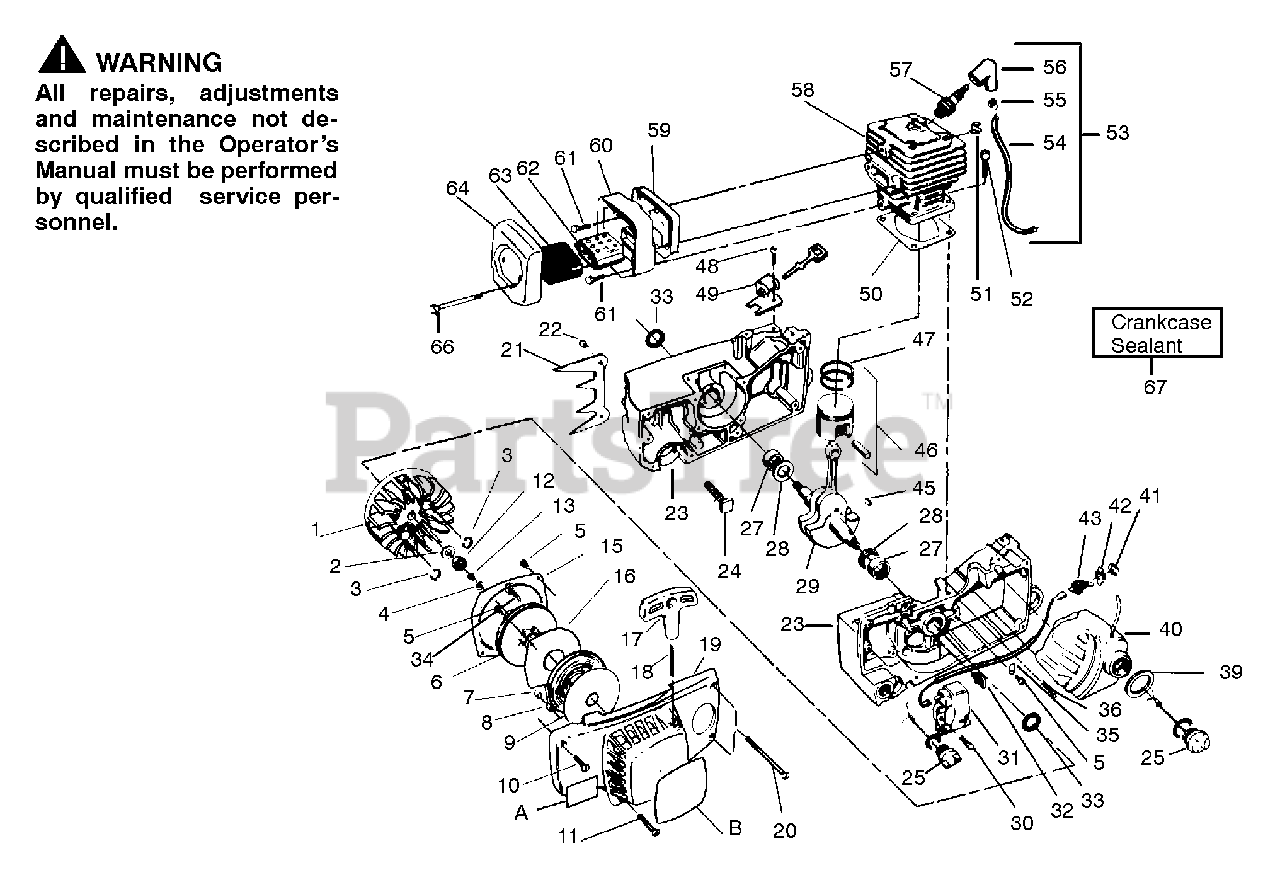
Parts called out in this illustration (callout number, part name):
1	Flywheel Ass'y.
2	Washer
3	Starter Dog Spring
6	Starter Pulley
7	Bushing Recoil Spring
8	Starter Recoil Spring
9	Disc. Recoil Spring
12	Flywheel Nut
13	Screw
15	Air Baffle
16	Disc. Recoil Spring
17	Starter Rope Handle
18	Rope Kit
19	Fan Housing Ass'y.
23	Crankcase Ass'y.
24	Bar Stud Replacement Kit (5/16")
25	Oil & Fuel Cap Kit
27	Crankshaft Bearing
28	Thrust Washer
29	Crankshaft Ass'y.
31	Ignition Module
33	Crankshaft Seal
35	Module Lead Clamp
39	Fuel Tank Neck Seal
40	Fuel Tank Ass'y.
41	Nut
42	Ignition Switch Plate
43	Toggle Switch
45	Flywheel Key
46	Piston Ass'y.
47	Piston Rings
49	Bracket & Bushing Ass'y.
50	Cylinder Gasket
53	High Tension Lead Ass'y.
54	High Tension Lead
55	Spark Plug Connector
56	Spark Plug Boot
57	Spark Plug
58	Cylinder
59	Muffler Back Plate
60	Muffler Body
62	Muffler Diffuser
63	Spark Arrestor Screen Screen
64	Muffler Cover
67	Crankcase Sealant
B	Instruction Decal
